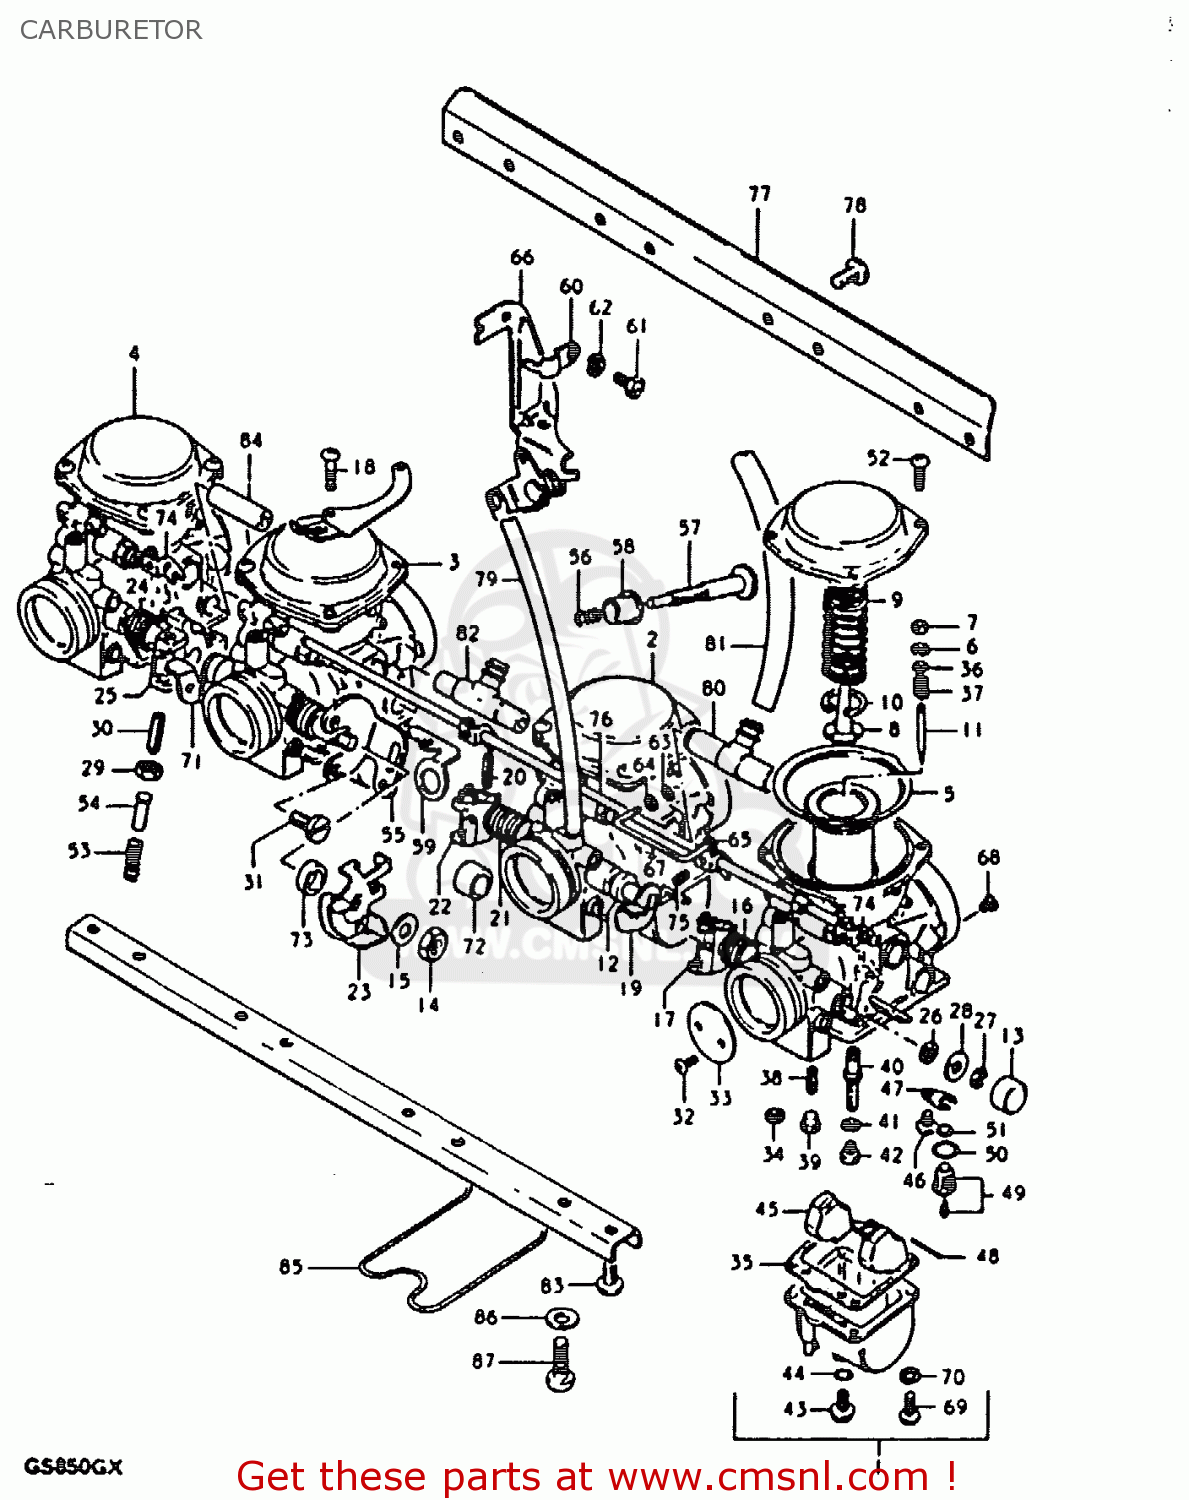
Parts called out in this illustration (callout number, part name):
1	CARBURETOR, NO. 1
2	CARBURETOR, NO. 2
3	CARBURETOR, NO. 3
4	CARBURETOR, NO. 4
5	DIAPHRAGM
6	CLIP,NEEDLE
7	RING
8	HOLDER,GUIDE
9	SPRING
10	E RING
11	NEEDLE, JET (5057-2)
12	GASKET,THROTTLE SHAFT (NAS)
13	CAP
14	NUT
15	WASHER
16	SPRING,THROTTLE SHAFT
17	SHAFT,THROTTLE
18	SCREW
19	SHAFT ASSEMBLY
20	PIN,THROTTLE SHAFT
21	SPRING,THROTTLE SHAFT
22	LEVER,THROTTLE SHAFT
23	LEVER ASSEMBLY,THROTTLE
24	SPRING,THROTTLE SHAFT
25	SHAFT,THROTTLE
26	SEAL
27	E RING
28	GASKET,THROTTLE SHAFT (NAS)
29	NUT
30	SCREW
31	SCREW
32	SCREW
33	VALVE,THROTTLE
34	GASKET (NAS)
35	GASKET,FLOAT CHAMBER (NAS)
36	WASHER
37	SPRING
38	JET, PILOT (42.5)
39	PLUG,NEEDLE JET
40	JET, NEEDLE (X-6)
41	WASHER,NEEDLE NOZZLE
42	JET
43	PLUG,DRAIN
44	GASKET (NAS)
45	FLOAT
46	SCREW
47	PLATE
48	PIN,FLOAT
49	VALVE ASSEMBLY,NEEDLE
50	O RING
51	FILTER
52	SCREW
53	SPRING,THROTTLE SCREW
54	PIN,THROTTLE LEVER
55	BRACKET,THROTTLE ADJUST
56	SPRING
57	SCREW
58	BUSH
59	BRACKET,THROTTLE ADJUST
60	BRACKET,STARTER
61	BOLT
62	LOCK WASHER
63	CAP,LEVER
64	SEAT,SPRING
65	LEVER ASSY
66	BRACKET
67	ROD,STARTER LEVER
68	JET,AIR
69	SCREW
70	LOCK WASHER
71	SHAFT ASSEMBLY
72	RING
73	RING
74	LEVER
75	SCREW
76	SHAFT,STARTER
77	BRACKET
78	SCREW
79	HOSE
80	NIPPLE
81	HOSE
82	NIPPLE
83	SCREW 6X12
84	NIPPLE
85	CLAMP
86	WASHER
87	SCREW
